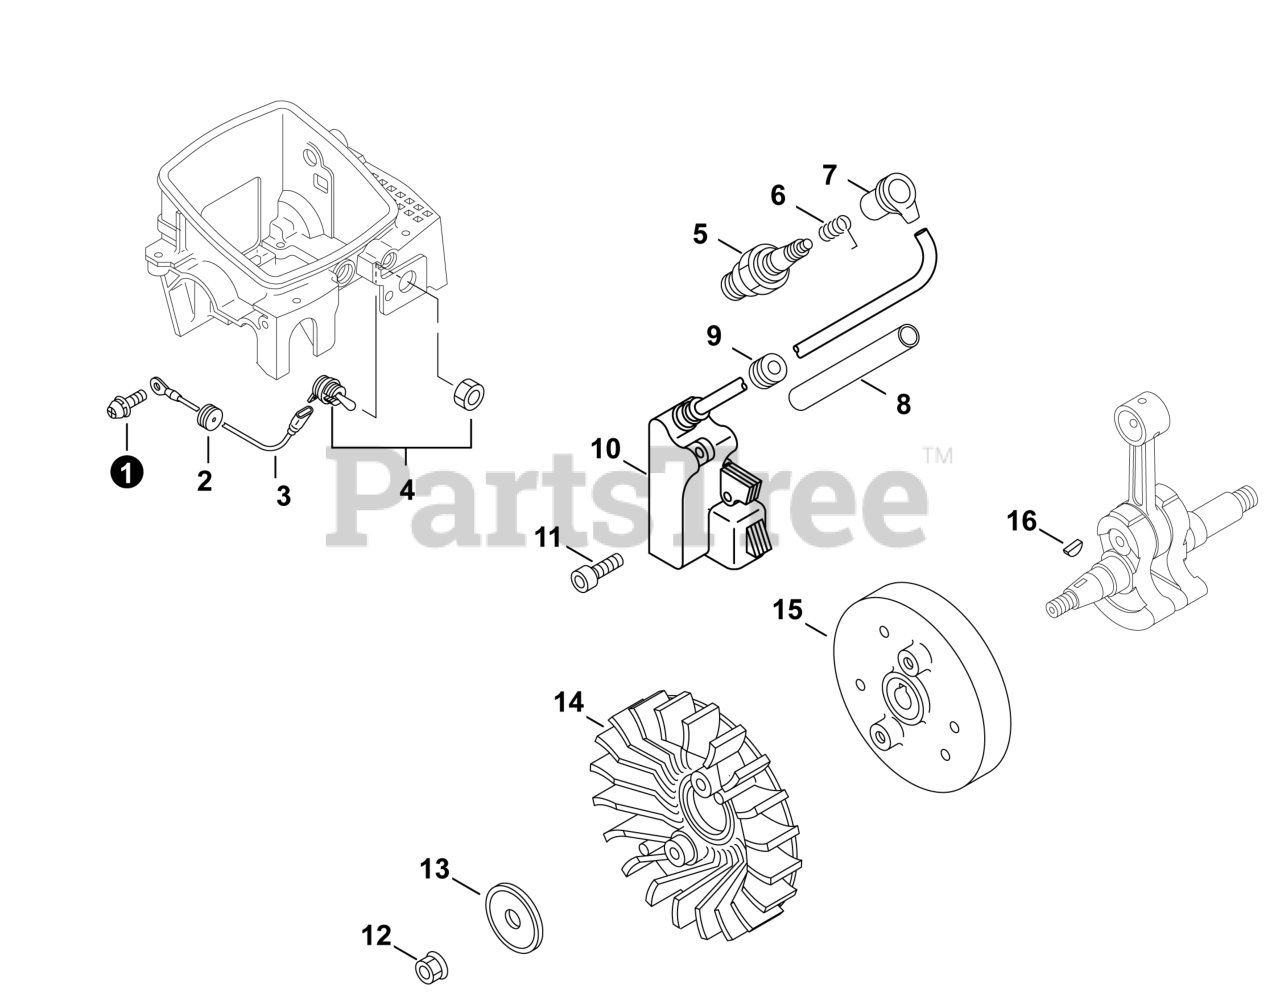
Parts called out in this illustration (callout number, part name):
1	SCREW 4×8
4	SWITCH, ON-OFF
5	SPARK PLUG - BPMR7A
6	TERMINAL, SPARK PLUG
7	CAP, SPARK PLUG
8	TUBE 7×8.6×45
10	COIL, IGNITION
11	BOLT 4×20
12	NUT, FLANGE M8×1.25
13	WASHER 8.2×31×0.8
14	FAN, COOLING
15	FLYWHEEL
16	KEY, WOODRUFF
